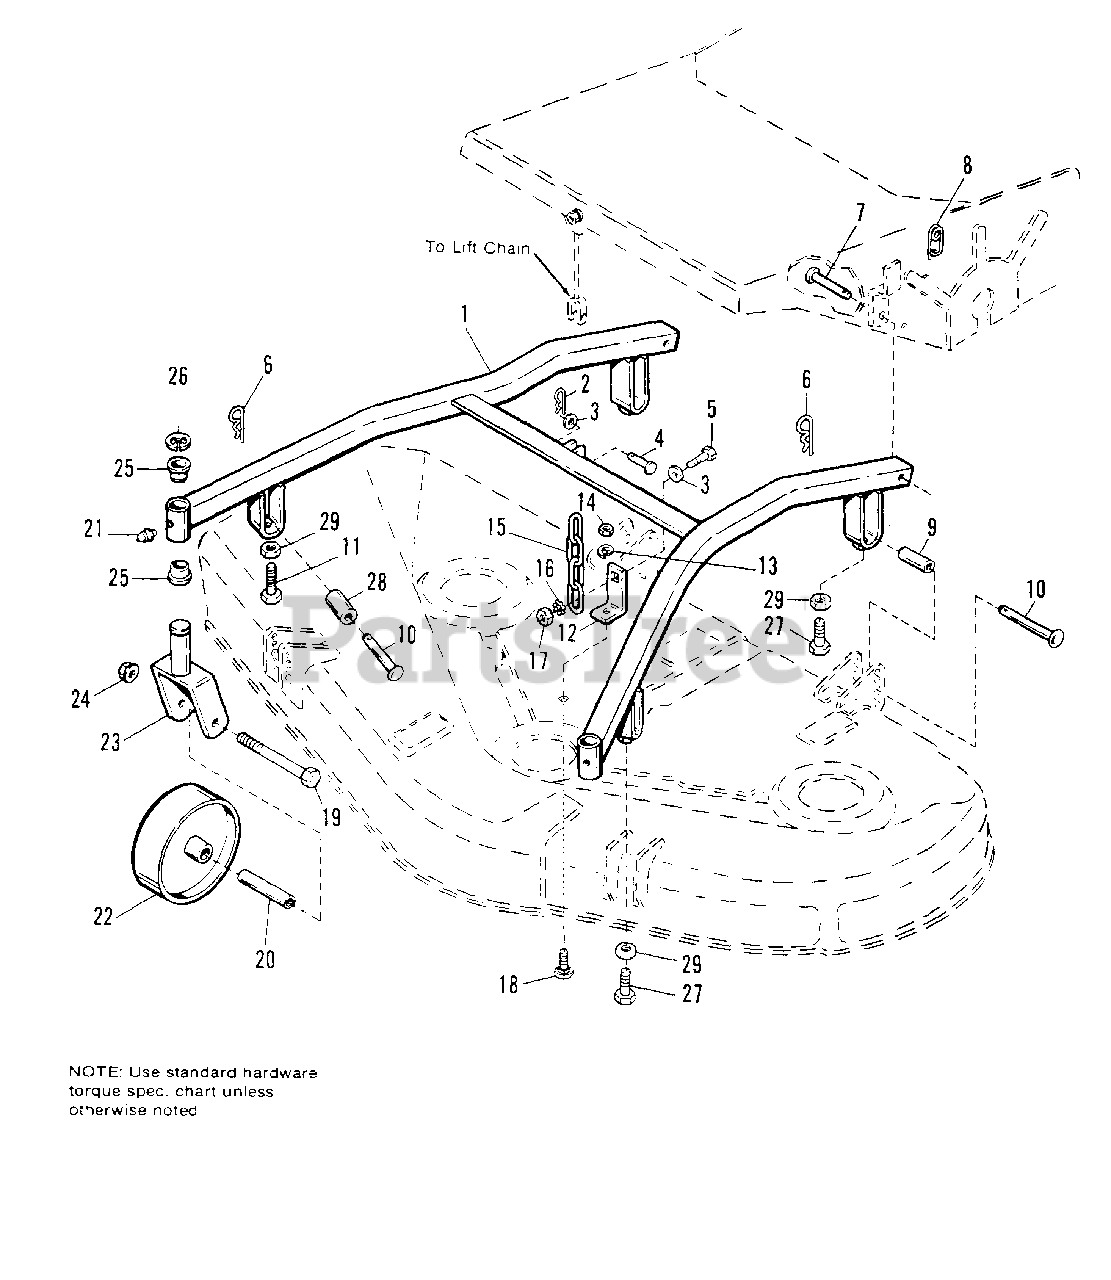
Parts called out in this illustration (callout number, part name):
1	ARM ASSY.
2	PIN, Quick
3	WASHER, 1/4
4	PIN, Lift Cable
5	CAPSCREW, Hex, 1/4-20 x 3/4
6	PIN, Quick
8	PIN, Safety
9	SPACER, Rear
11	CAPSCREW, Hex, 3/8-16 x 2
12	BRACKET, Lift
13	LOCKWASHER, 5/16
14	NUT, Hex, 5/16-18
15	CHAIN, Lift
16	LOCKWASHER, Ext., 1/4
17	NUT, Hex, 1/4-20
18	CARRIAGE BOLT, 5/16-18 x 3/4
19	CAPSCREW, Hex, 1/2-13 x 3-1/2
20	SPACER, Wheel
21	FITTING, Lube, 1/4
23	YOKE ASSY., Wheel
24	NUT, Lock, 1/2-13
27	CAPSCREW, Hex, 3/8-16 x 1-1/2
28	SPACER, Front
29	NUT, Hex Jam, 3/8-16
